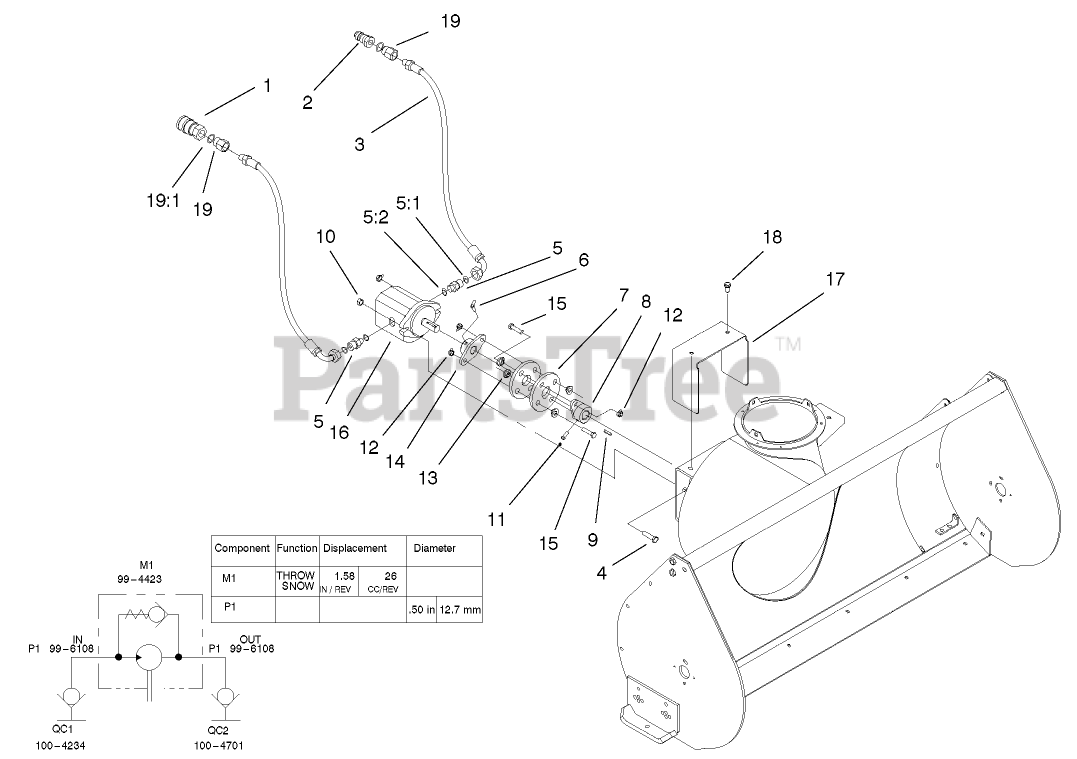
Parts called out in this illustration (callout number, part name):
1	COUPLER-FACE, FLUSH
2	NIPPLE-CONNECT, PRESSURE
3	HOSE-HYD
4	SCREW-HH
5	FITTING-STRAIGHT
5:1	O-RING
5:2	O-RING
6	SCREW-SET
7	COUPLING-RUBBER
8	HUB-COUPLER
9	KEY
10	NUT-LOCK, NI
11	SCREW-SET, SQH
12	NUT-LOCK, NI
13	SPACER
14	HUB-PUMP
15	SCREW-HH
16	MOTOR-HYDRAULIC
17	SHIELD-MOTOR
18	SCREW-HWHTF
19	ADAPTER-HYD
19:1	O-RING
